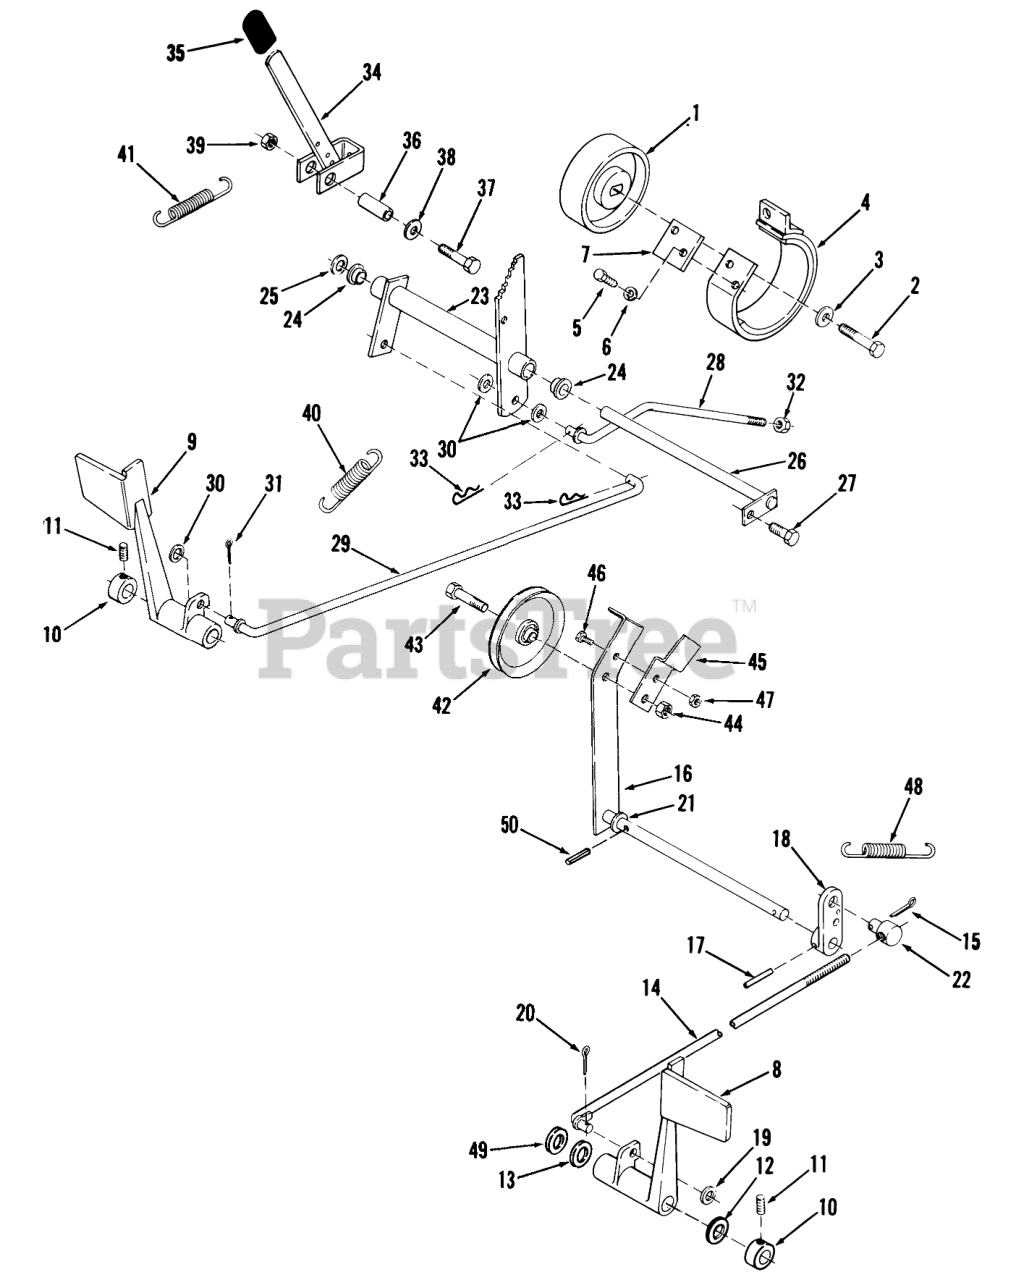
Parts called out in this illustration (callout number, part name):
1	DRUM-BRAKE
2	Bolt
3	WASHER
4	BRAKE BAND ASM
5	H H C S
6	Washer
7	Plate-Stop
8	Clutch Pedal
9	PEDAL-BRAKE R
10	Collar
11	SCREW-SET
12	WASHER-BOWED
13	WASHER
14	ROD AND GUIDE ASM
15	Pop Rivet
16	Clutch Idler Arm
17	PIN-SPIROL
18	Arm-Clutch Rod
19	WASHER-NYLON
20	Pop Rivet
21	SHIM-WASHER
22	TRUNNION
23	Bellcrank Assy
24	BUSHING-FLANGED
25	Washer
26	ROD ASM
27	SCREW
28	ROD-REAR BRAKE
30	WASHER-NYLON
31	Pop Rivet
32	NUT
33	Hairpin
34	ASSY-BRAKE LEVER WAB
35	GRIP
36	SPACER
37	Bolt
38	Washer
39	LOCKNUT-FLANGE
40	SPRING-BRAKE
41	SPRING-EXTENSION
42	PULLEY-IDLER
43	BOLT-SPECIAL HEX
44	Nut
45	SWITCH-ACTUATOR
46	H H C S
47	Nut
48	SPRING-CLUTCH
49	Washer
50	PIN-SPIROL
